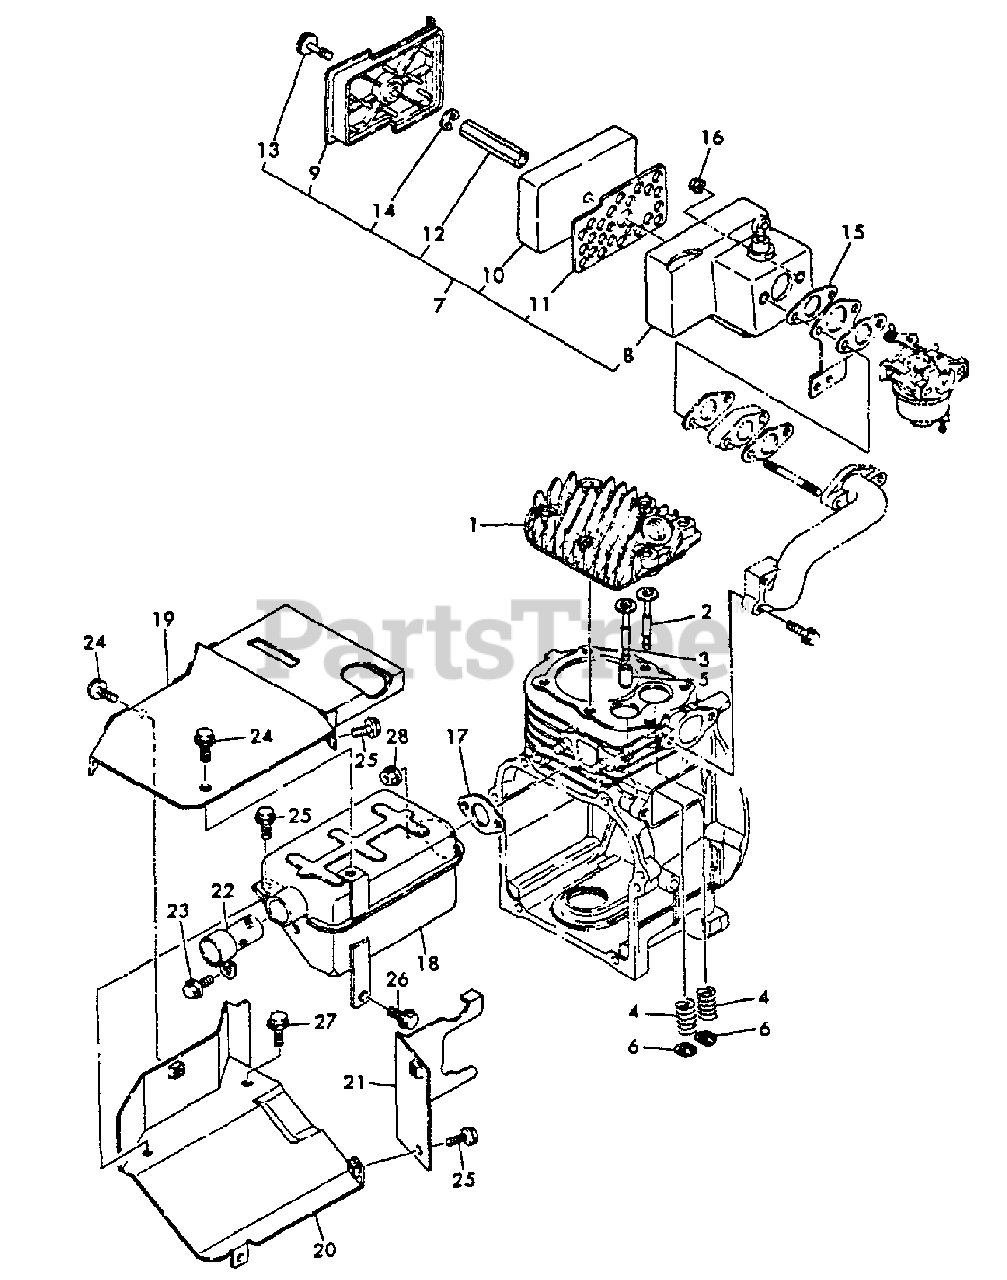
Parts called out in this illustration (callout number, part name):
1	HEAD, CYLINDER
2	VALVE, INTAKE
3	VALVE, EXHAUST
4	SPRING, VALVE
5	GUIDE, VALVE
6	RETAINER, VALVE
7	CLEANER ASSY, AIR
8	CASE, AIR FILTER
9	COVER, AIR FILTER
10	FILTER, AIR
11	HOLDER, ELEMENT
12	NUT
14	RING, RETAINING - 5
15	GASKET
16	U-NUT M6
17	GASKET, EXHAUST
18	SILENCER
19	GUIDE - A
20	DRIVESHAFT GUIDE ASSY
21	GUIDE C
22	ARRESTOR, SPARK
23	BOLT - 6×8 -- PLATED
24	BOLT - 6×8 -- PLATED
25	BOLT - 6×8 -- PLATED
26	BOLT - 6×12 -- PLATED
27	BOLT - 6×8 -- PLATED
28	U-NUT M6
